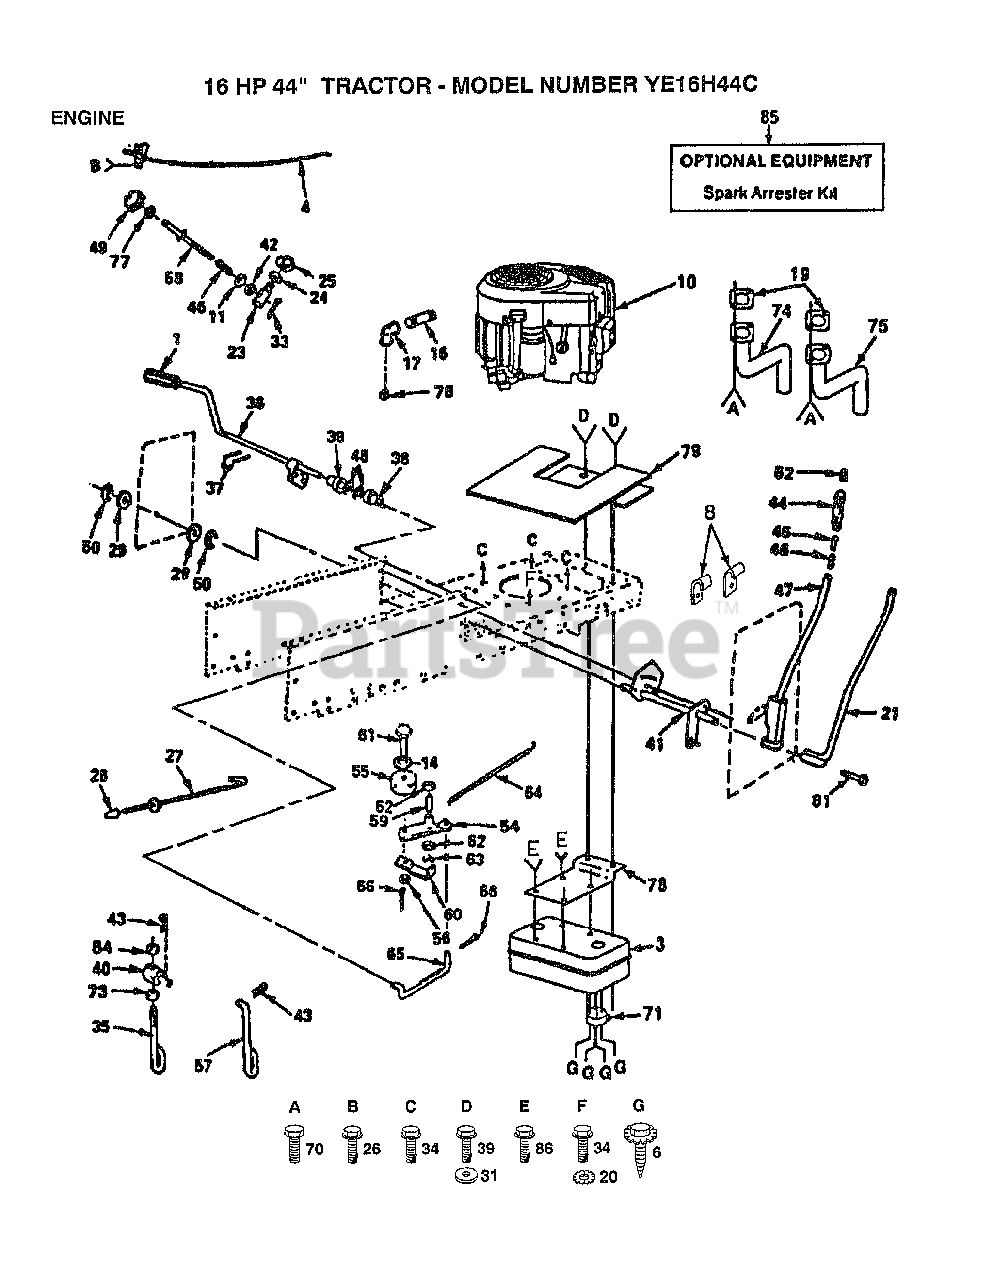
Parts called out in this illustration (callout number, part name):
1	PEDAL COVER T
4	THROTTLE CONTROL
8	CLIP T
11	WASHER
14	WASHER
16	PIPE NIPPLE LT
17	ELBOW
20	LOCKWASHER
21	LEVER ROD LT
23	TRUNION LT
24	WASHER
25	KLIP RING
26	SCREW LT
27	BRAKE PARK ROD
28	PLUNGER CAP T
29	WASHER
31	WASHER
34	SCREW LT
35	PIVOT PIN T
38	NYLON BEARING
39	SCREW
42	NUT T
44	GRIP
46	SPRING T
48	WASHER LT
50	E-RING
54	ARM IDLER
57	LIFT LINK LT
58	ROD LIFT LT
59	"LY, BEARING"
60	RETAIN BELT
62	WASHER LT
63	KLIP RING
64	"SPRING, RETURN LT"
65	"LINK, CLUTCH T"
66	COTTER PIN
71	DEFLECTOR.222573
73	NUT
74	TUBE ASSY EXH LH
75	TUBE ASSY EXH RH
77	NUT
78	BRACKET MUFFLER
81	"BOLT,HEX"
86	SCREW ST
